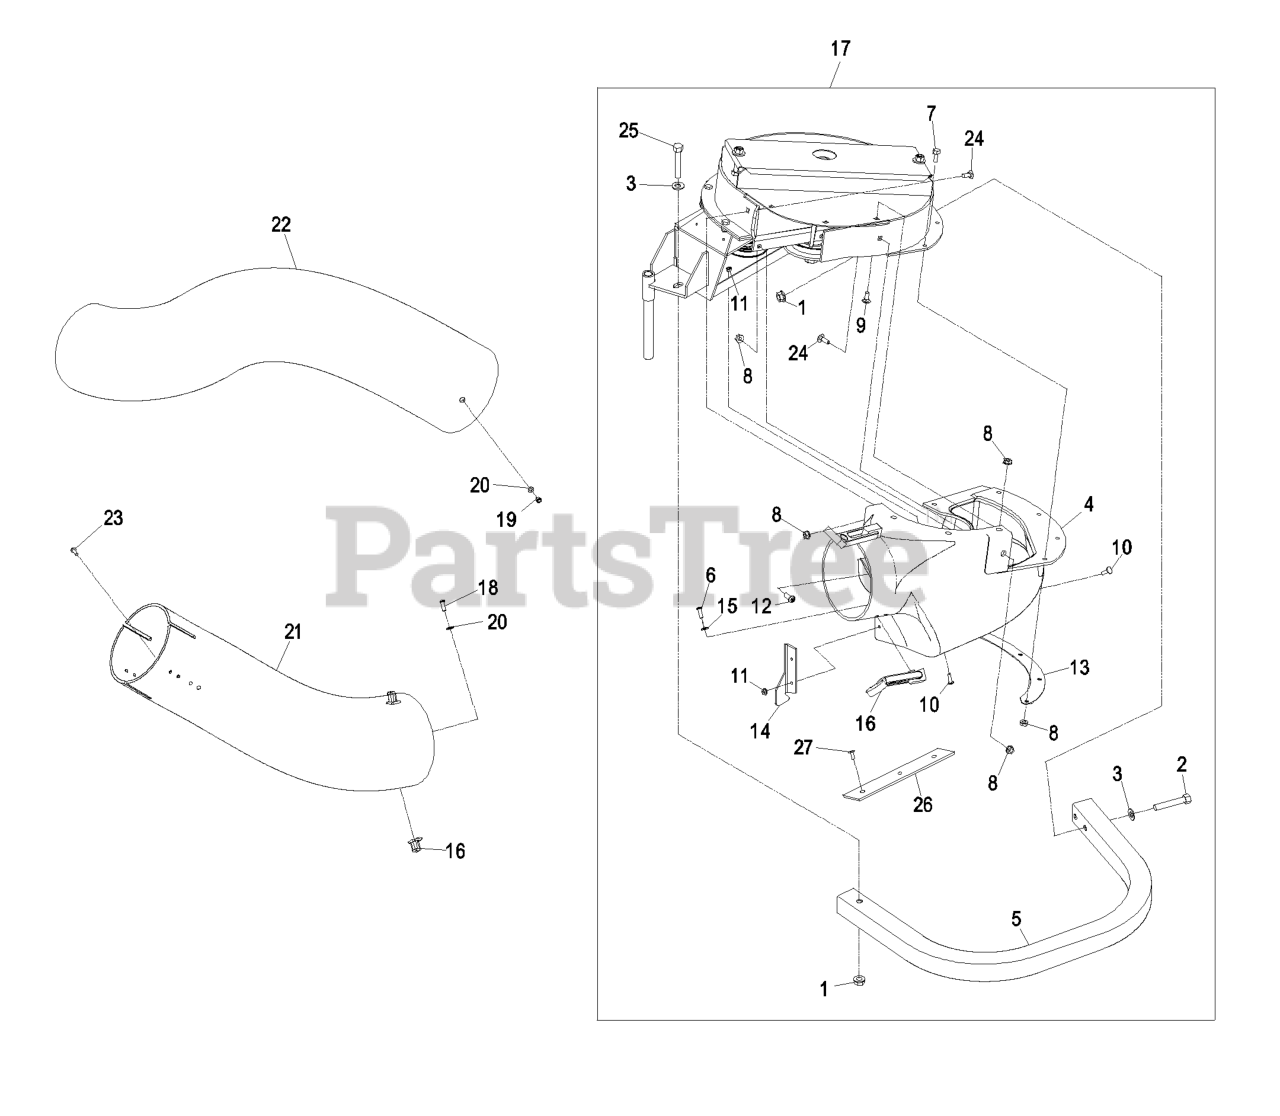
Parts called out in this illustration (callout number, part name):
1	NUT-HHF, WHIZ
2	SCREW-HH
3	WASHER-FLAT
4	ASM,BLOWER CHUTE LHP
6	SCREW-PPH
7	SCREW-HH
9	SCREW-CARR
10	SCREW-HEAD, TRUSS
11	NUT-HF
13	PLATE-BACKING, BLOWER
14	PLATE, FILLER
15	WASHER-FLAT
16	LATCH DRAW
17	ASM,BLOWER
18	SCREW-PPH
19	NUT-LOCK, NI
20	WASHER-FLAT
21	KIT,LOWER TUBE
22	TUBE,UPPER 46/50
23	SCREW-HWH
24	BOLT-CARR
25	SCREW-HH
26	PLATE-REINFORCEMENT
27	RIVET-BLIND
